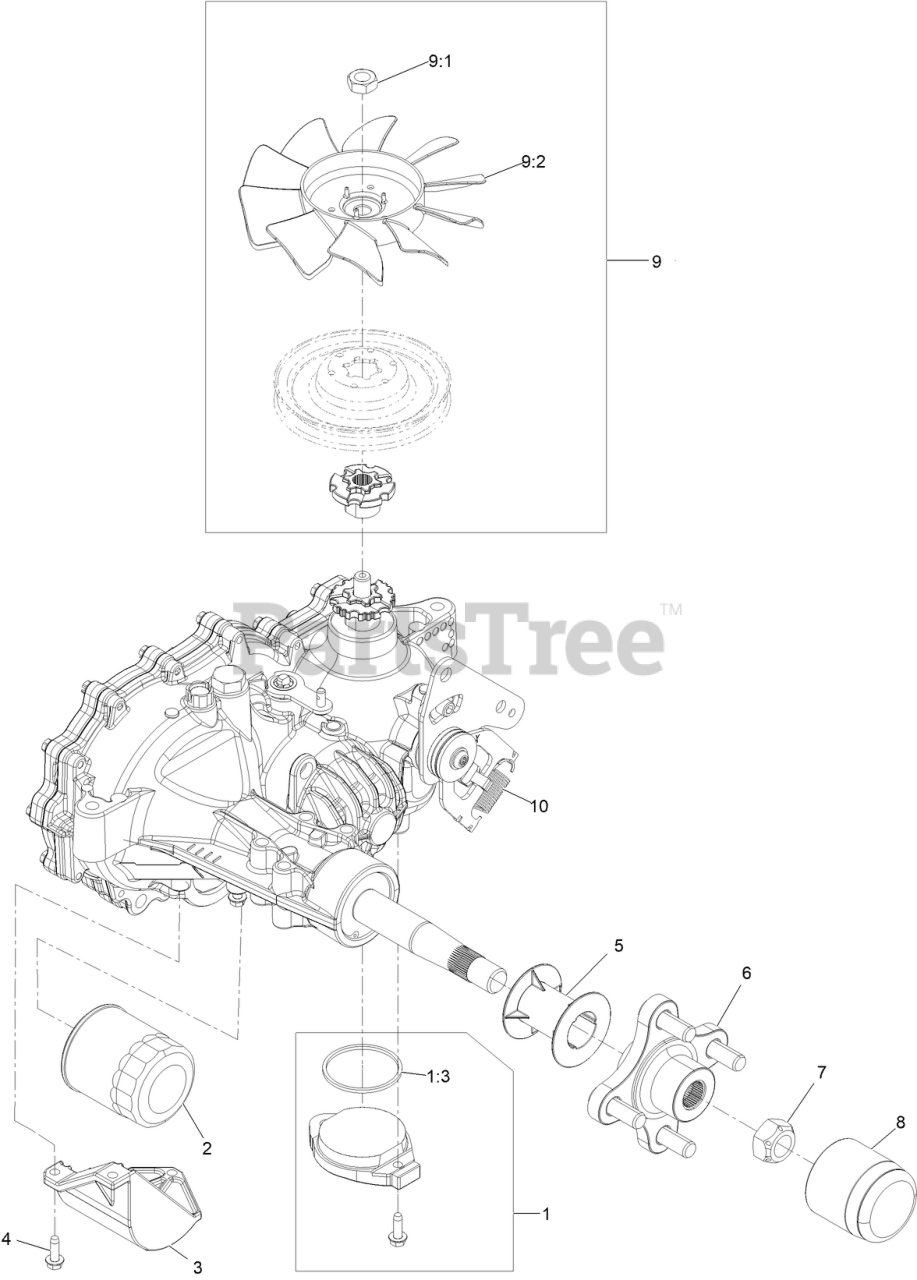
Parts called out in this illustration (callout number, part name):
1	CHARGE KIT
1:3	O RING-SEAL
2	ELEMENT-OIL FILTER, HYD
3	GUARD-FILTER, RH
5	TUBE-AXLE
6	HUB-OFFSET
7	NUT-HUB
8	CAP-AXLE, LONG
9	Fan And Pulley Kit
10	SPRING-EXTENSION
